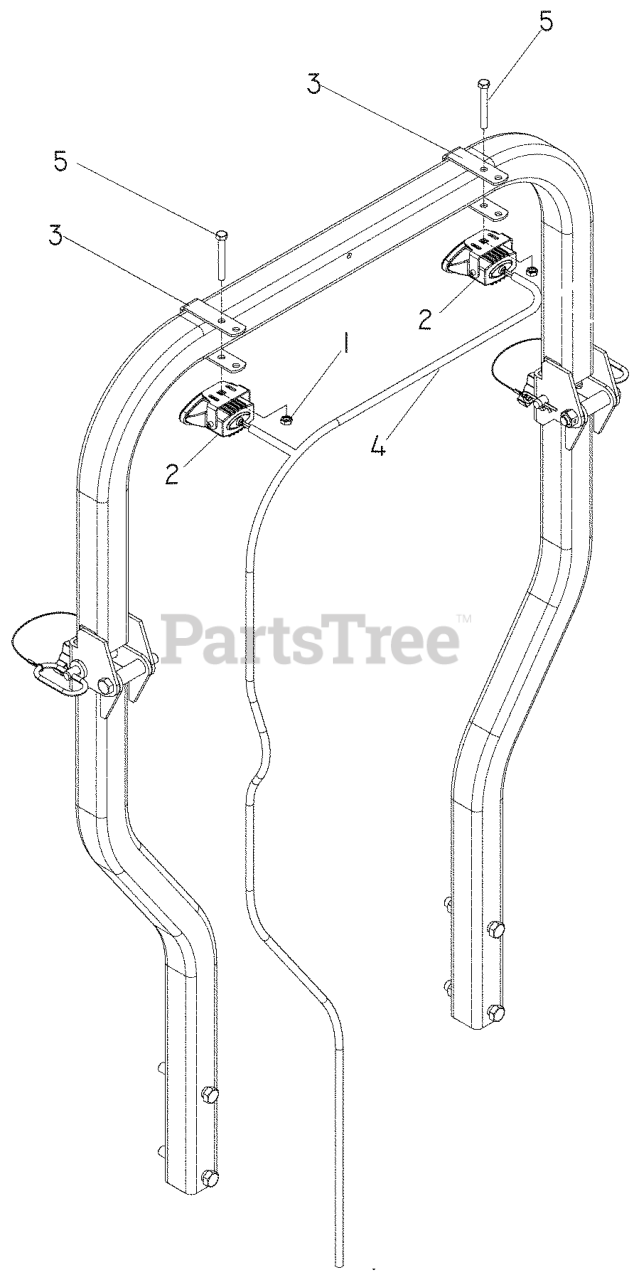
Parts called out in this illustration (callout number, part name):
1	NUT 5/16-18 HEX JAM ZD
2	LIGHT 35W W/BRKT
3	LIGHT MOUNTING BRACKET
4	LIGHT HARNESS
5	BOLT 5/16C X 2 1/2
